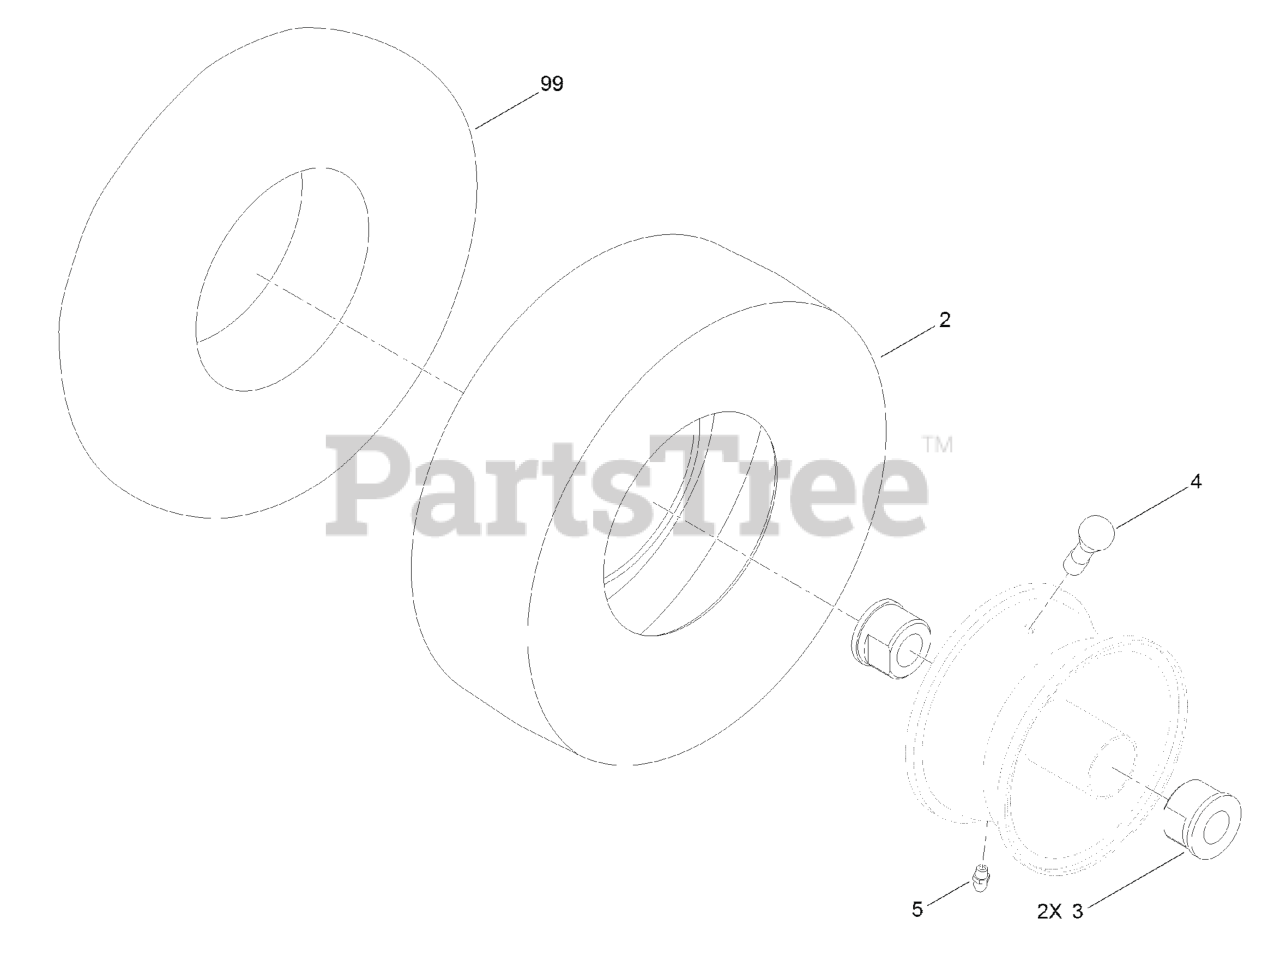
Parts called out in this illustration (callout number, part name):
3	BUSHING-FLANGE
4	Stem-Valve
5	FITTING-GREASE
99	TUBE-INNER
